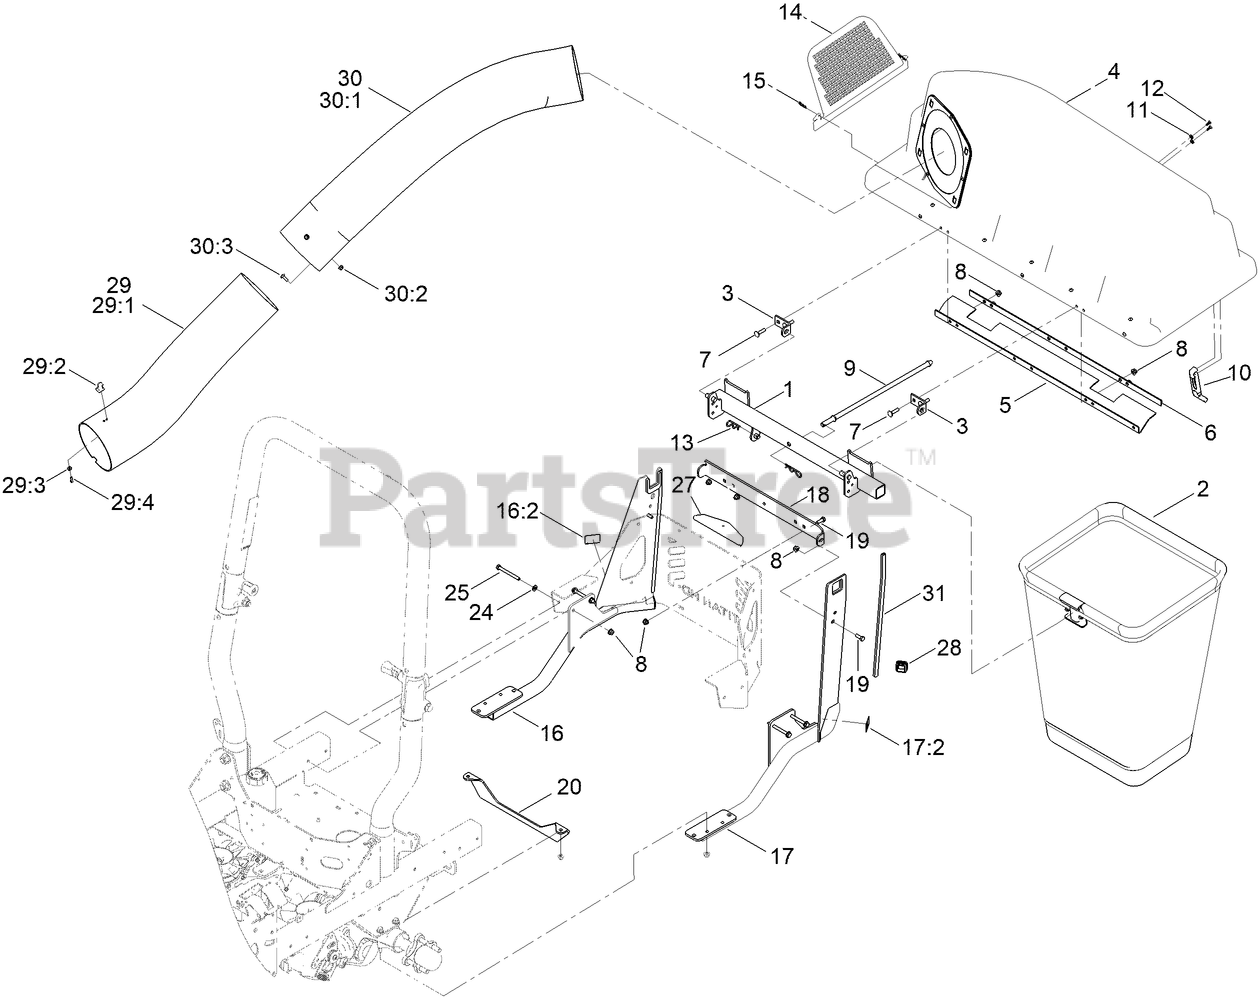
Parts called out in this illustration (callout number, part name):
1	FRAME PIVOT ASM
2	BAG AND FRAME ASM
3	BRACKET-PIVOT, HOPPER
4	BAGGER HOOD ASM
6	PLATE-BACKING
7	SCREW-CARR
8	NUT-HF, NI
9	ROD-HOLD DOWN, HOOD
10	LATCH-RUBBER
11	WASHER-FLAT
12	SCREW-PLASTITE
13	PIN-HAIR
14	SCREEN-BAGGER
16	RH BAGGER SUPPORT ASM
16:2	DECAL-WARNING
17	LH BAGGER SUPPORT ASM
17:2	DECAL-WARNING
18	ANGLE - SUPPORT, BAGGER
19	SCREW-HH
20	SUPPORT-TRANSMISSION
24	WASHER-PLAIN
25	SCREW-HH
27	COVER-HITCH
29	LOWER TUBE ASM
29:1	TUBE-LOWER
29:2	LATCH-KEEPER
29:3	WASHER-FLAT
29:4	SCREW-PPH
30	UPPER TUBE ASM
30:1	TUBE-UPPER
30:2	NUT-HF
31	STRIP-TRIM
